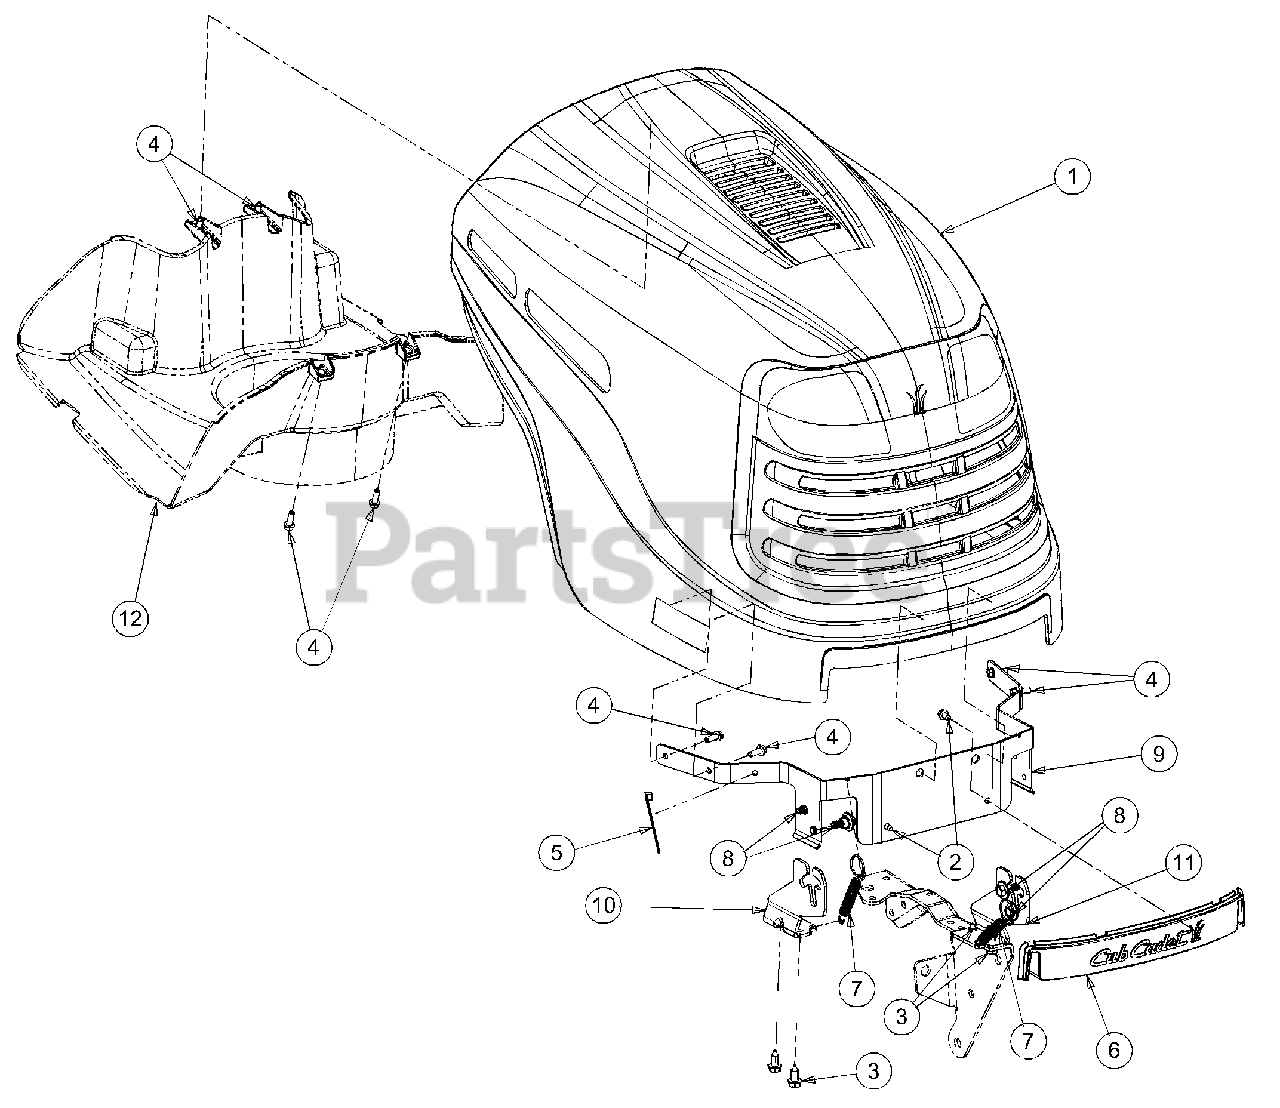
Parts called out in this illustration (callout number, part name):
1	Hood
1	Headlight Harness
1	Miniature Lamp, 12 V
1	Lamp Socket
1	Headlight Lens
1	Headlight Lens Reflector, LH
1	Headlight Lens Reflector, RH
2	Screw, Hx. Wash, Hd,Tapp 1/4-20 x .5
3	Self-tapping Screw, 5/16-18 x .625
4	Screw, 1/4-15 x .75
5	Cable Tie
6	Cover, Front Hood
7	Spring, .46 x 4.12
8	Shoulder Screw, .43 x .29 x 5/16-18
12	Hood Plenum (LT1022)
